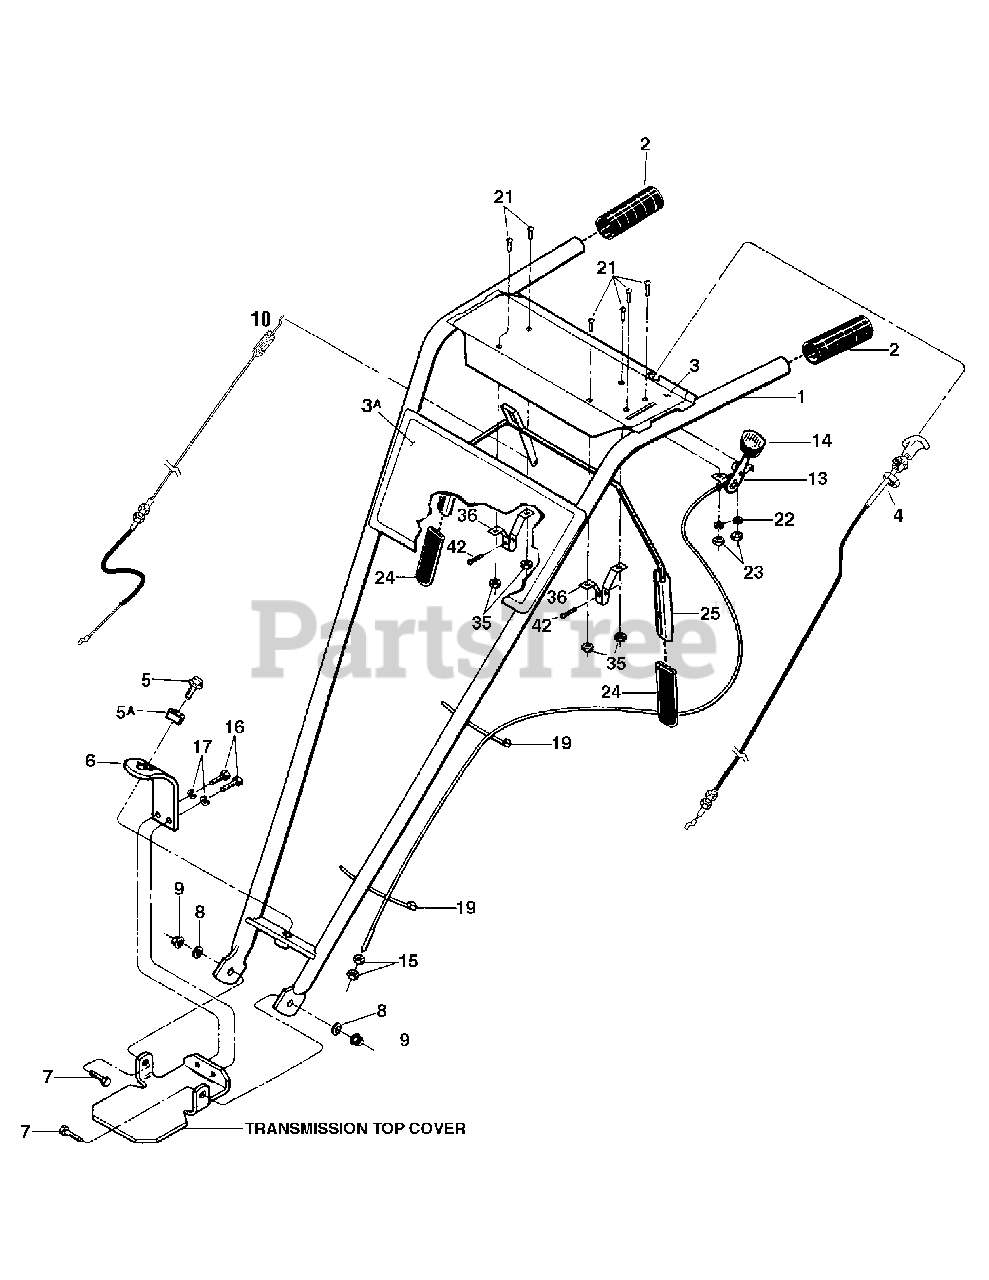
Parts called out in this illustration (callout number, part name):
1	Handlebars
2	Grip
3	Decal, Control Panel
3A	Decal, Model Name/Logo (for model 663E)
3A	Decal, Model Name/Logo (for model 665B)
4	Reverse Clutch Control Cable
5	Height Adjustment Screw
5A	Washer, Keyed
6	Bracket, Handlebar Height Adjustment
7	Hex Hd. Screw, 3/8-16 x 1 (specify Grade 5 if ordering part locally)
8	Washer, Plain (flat) 3/8, S.A.E.
9	Hex Locknut, 3/8-16
10	Cable, Forward Clutch Control
13	Wheel Gear Control and Cable Assembly
14	Knob, Wheel Gear Control Lever
15	Hex Nut, 5/16-24
16	Hex Hd. Screw, 3/8-16 x 5/8 (specify Grade 5 if ordering part locally)
17	Lockwasher, 3/8
19	Cable Ties, Plastic Screw, #10-32 x 1/2
21	Round Hd. Screw #10-32 x 1/2
22	Lockwasher, #10
23	Hex Nut, #10-32
25	Bail w/ Grips, Forward Clutch Control
36	Bracket, Bail support
42	Hex Flange Screw, self-tapping, 1/4-20 x 1/2*
